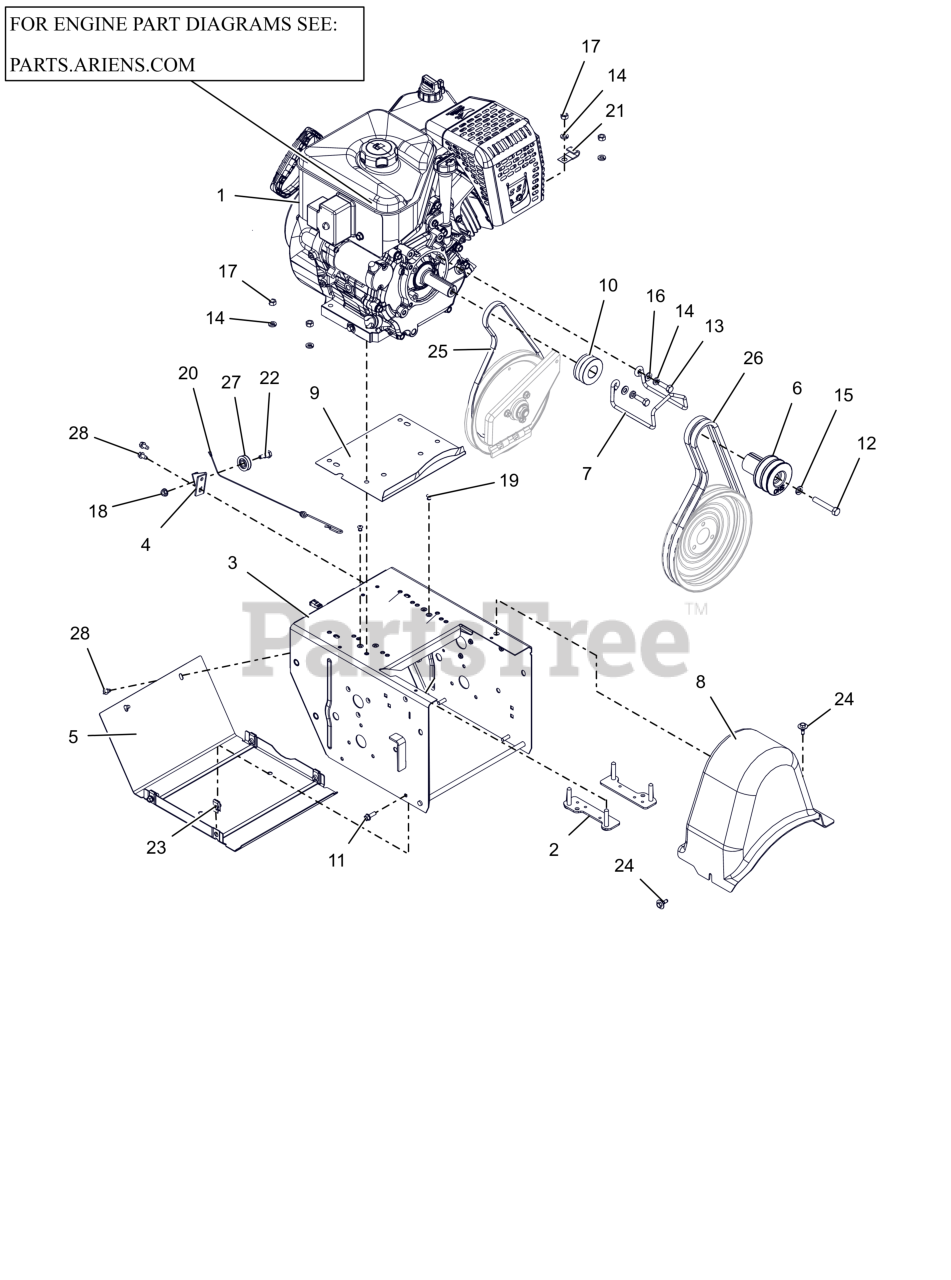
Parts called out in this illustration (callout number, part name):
1	ENGINE, AX414 GEN3 120V/60W
2	STRAP, BOLT-LARGE
3	FRAME, MAIN - 14GA DELUXE (ORANGE)
4	BRACKET, CABLE PULLEY
5	COVER, BOTTOM
6	SHEAVE,ATTACHMENT-SHO 2 GRV
7	FINGER, BELT
8	COVER, BELT-LARGE
9	BAFFLE, WATER - LARGE BLOCK
10	SHEAVE, TRACTION (KEYLESS)
11	BLT, HWH .25-20X.75 G5 ZCC
12	BLT, HEX .38-24X2.25 G5 ZCC
13	BLT, HEX 0.3125-24X1 G5 ZCC
14	WSHR, LK-HVY .312X.097 ZCC
15	WSHR,LK-REG .375X.094 ZCC
16	WSHR,FLT .344X.688X.065 ZCC
17	NUT, HEX .312-18 ZCC
18	NUT-LK-TOP-FLG .250-20 GF ZCC
19	RVT, POP .1875 ZCC
20	CABLE, LOWER TRACTION,SS & PRO
21	J-CLAMP
22	BOLT, SHLDR -.375 X .375 X .25-20
23	NUT-RTNR .25-20X.56
24	SCR-TAP .25-20X.5 CAPTIVE
25	V-BELT, 3L-WRAPPED
26	V-BELT, HA-RAW EDGE (SET)
27	PULLEY, CABLE
28	SCR-TAP .25-20X.50 HWH ZCC
